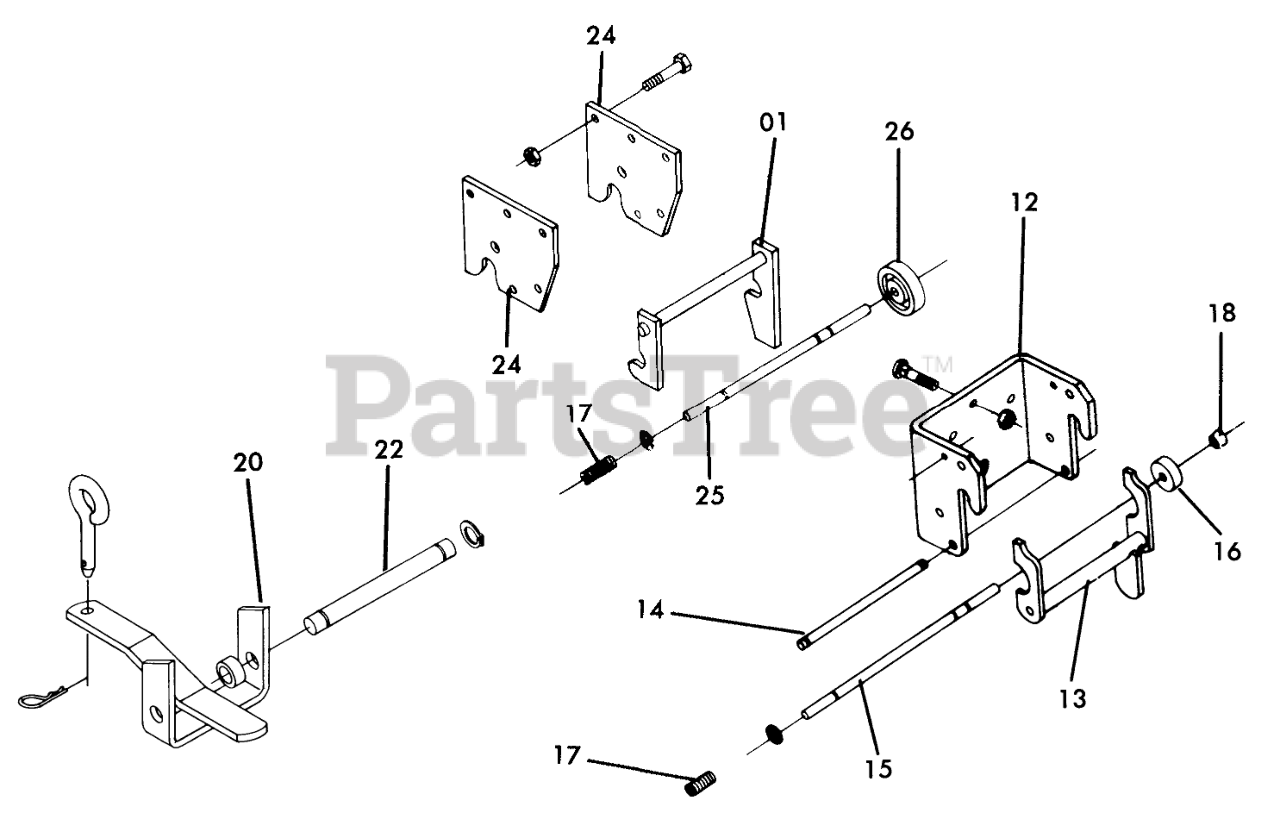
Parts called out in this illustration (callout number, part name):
01	ASSY MID HITCH LA R
12	Front Hitch
13	Latch Assembly
14	ROD-LATCH PIVOT
14	Lock Rod
15	ROD-LOCK
15	Lock Rod
17	SPRING
18	Cap
20	Hitch
22	Pin
22	Spacer
22	RING-SNAP, EXTERNAL
22	Pin-Tool
22	Hairpin Cotter
24	Hitch Plate
25	Lock Rod
26	BOLT
26	Nut
